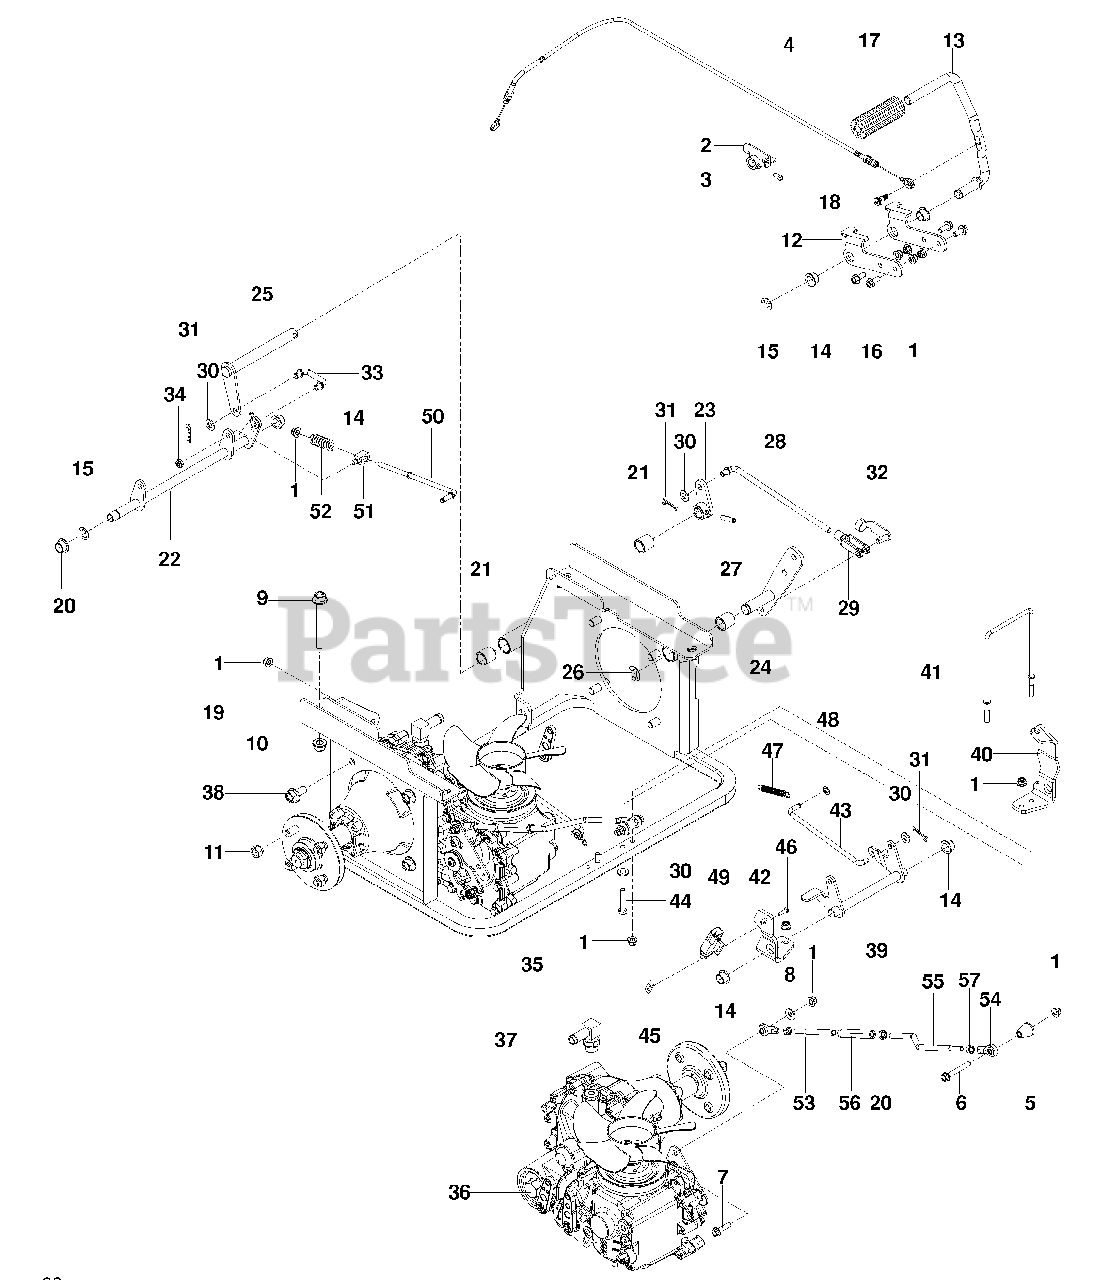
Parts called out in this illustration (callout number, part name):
1	Nut 5/16-18 Hex Flg Nyloc
2	Bolt 7/16-20 X 1 1/2 Hex Nyl
3	Screw 5/16-18 Sq Set
4	Cable, 2 Speed
5	Spacer 1" Tappered
6	Screw 5/16-18 X 2 1/4 Hex Flg
7	Screw 5/16-18 X 1 1/4 Tpblt
8	Washer 5/16 Flt
9	Bolt 1/2-13 X 4 Hex Flg
10	Nut 1/2-13 Flg Nyloc
11	Nut 1/2 Lug
12	Bracket, Pedal
13	Lever, Pedal
14	Bushing .625 Flange
15	E-Ring, .625
16	Screw 5/16-18 X 3/4 Hex Flg
17	Pad, Foot Pedal
18	Bolt 3/8 X 1 1/4 Shldr
19	Frame, Zt5400
20	Nut 3/8-24 Jam
21	Bushing, Sleeve 3/4 X 1
22	Shaft, Lower
23	Arm, Rt Brake
24	Lever, Lower Brake
25	Shaft, Brake
26	E-Ring 3/4
27	Roll Pin 5/16" Dia.
28	Linkage, Brake Upper
29	Yoke 3/8-24
30	Washer 3/8 Sae Flt
31	Hairpin Cotter
32	Pin 3/8 Clevis Spring
33	Linkage, Brake, Middle
34	Nut 5/16-18, Nyloc Insert
35	Zt5400, Left
36	Zt5400, Right
37	Fitting, 4601-10-10
38	Screw 1/2-13 X 1 Hex Flg
39	Crank, Two Speed
40	Bracket, Two Speed, Lt
41	Rod, Belt Keeper
42	Bracket, Two Speed, Rt
43	Linkage, Two Speed
44	Bolt 5/16-18 X 1 3/4 Hex Nyl
45	Tapped Plate
46	Screw #10-24 X 3/4 Skt
48	Pushnut
49	Switch, Plunger, Sealed
50	Linkage, Brake Lower
51	Swivel, Brake
53	Linkage, Control, Ft
55	Rod, Control
56	Turnbuckle 3/8
57	Nut 5/16-24
